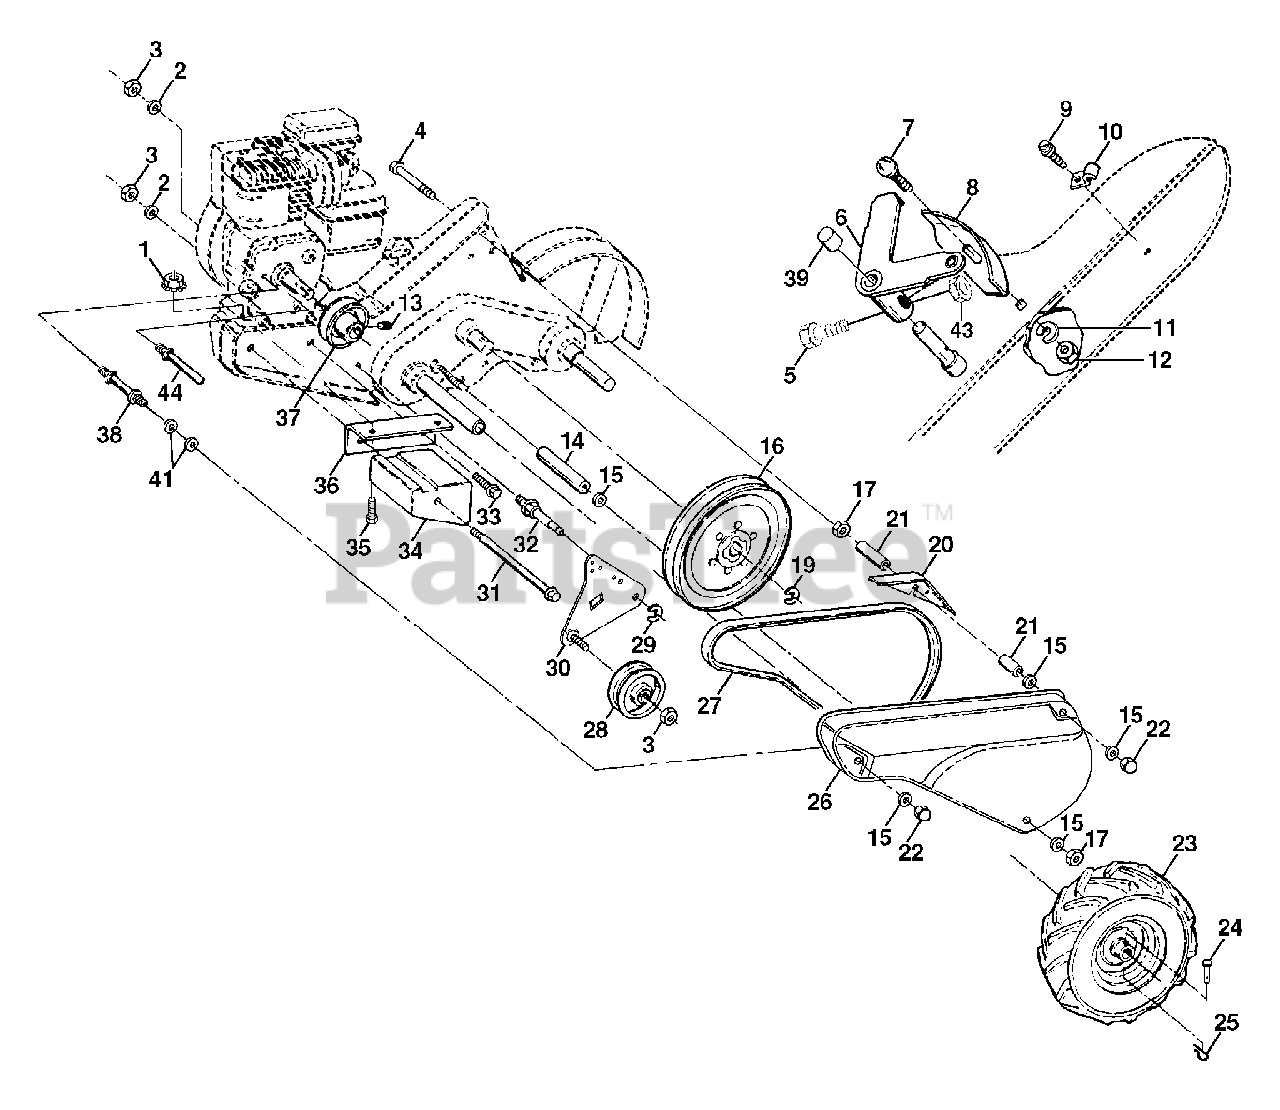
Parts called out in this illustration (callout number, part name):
1	Nut, Keps 5/16-18
2	Washer, Lock 3/8
3	Nut, Hex 3/8-16
4	Bolt, Hex 5/16-18 x 4-1/4
5	Screw, Shift Lever
6	Lever, Shift
7	Bolt, Carriage 1/4-20 x 1/2 Gr. 5
8	Plate, Shift Indicator
9	Screw, Hex, Washer Head, Slotted #10-24 x 1/2
11	Washer, Lock 1/4
12	Nut, Hex 1/4-20
13	Screw, Set, Hex 5/16-18 x 3/8
14	Spacer, Split 0.327 x 0.42 x 2.68
15	Washer 11/32 x 11/16 x 16 Ga.
16	Sheave, Transmission
17	Nut, Hex 5/16-18
19	Retainer, Ring
20	Guard, Pinch Point
21	Spacer, Split 0.327 x 0.42 x 1.688
22	Nut, Cap 5/16-18
23	Rim
23	Tire Valve
24	Rivet, Drilled
25	Clip, Hairpin
26	Guard, Belt
27	Belt, V
28	Pulley, Idler
29	Ring, Klip
30	Bracket, Idler
31	Bolt, Hex 5/16-16 x 12
32	Shaft, Idler Arm
33	Bolt, Hex 3/8-16 x 1
34	Counterweight, L. H.
35	Bolt, Hex 5/16-18 x 2
36	Bracket, Reinforcement, L. H.
37	Sheave, Engine
38	Stud, Belt Guard
39	Cap, Plunger Blk
41	Washer 11/32 x 1 x 10 Ga.
43	Nut, Lock #10-24
44	Belt, Keeper
